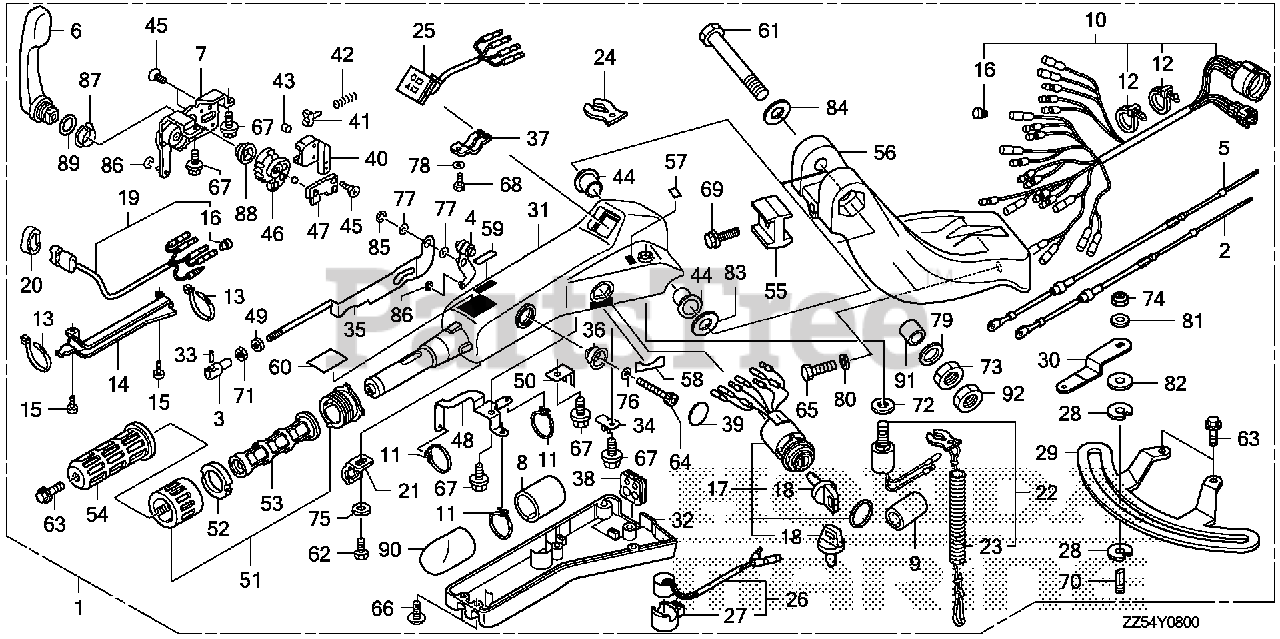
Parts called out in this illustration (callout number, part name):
1	HANDLEBAR KIT *NH282MU* (OYSTER SILVER METALLIC-U)
2	CABLE, THROTTLE
3	PIVOT, THROTTLE CABLE
4	ARM, THROTTLE
5	CABLE, SHIFT
6	LEVER, SHIFT
7	FRAME ASSY., SHIFT
8	TUBE (38.1X40)
9	TUBE
10	CABLE ASSY., LONG HANDLE (A)
11	BAND (CONVEX CV-150)
12	BAND (CONVEX CV-200)
13	BAND (CONVEX)
14	COVER, WIRE
15	SCREW
16	PLUG, CONNECTOR (INNER)
17	SWITCH ASSY., COMBINATION
18	KEY ASSY., COMBINATION SWITCH (35100-ZV5-003 ONLY)
19	SWITCH ASSY., POWER TILT
20	GROMMET
21	HOLDER, SWITCH
22	SWITCH ASSY., EMERGENCY STOP
23	WIRE, EMERGENCY
24	CLIP, EMERGENCY LOCK
25	LAMP ASSY., INDICATOR
26	BUZZER ASSY., WARNING
27	SUSPENSION, WARNING BUZZER
28	BLOCK, FRICTION
29	PLATE, FRICTION
30	LEVER, FRICTION
31	HOUSING *NH282MU* (OYSTER SILVER METALLIC-U)
32	COVER, HANDLEBAR (LOWER)
33	PIN, THROTTLE CABLE
34	BRACKET, CABLE
35	PLATE ASSY., LOCK
36	STOPPER
37	PLATE, GUIDE
38	GROMMET
39	CAP
40	GUIDE, SPRING
41	ACTUATOR
42	SPRING, COIL
43	ROLLER
44	BUSH, HANDLEBAR
45	SCREW (M5X14)
46	GEAR, SHIFT
47	PLATE, BALL GUIDE
48	BRACKET
49	ROD, GROMMET
50	CLAMP, BRACKET
51	GRIP ASSY., THROTTLE FRICTION
52	PAD, THROTTLE FRICTION
53	PIPE, GRIP
54	RUBBER, GRIP
55	BLOCK, HEIGHT ADJUSTER
56	BRACKET, STEERING *NH282MU* (OYSTER SILVER METALLIC-U)
57	MARK, EMERGENCY SWITCH INDICATION
57	MARK, EMERGENCY SWITCH INDICATION (EU)
58	MARK, STARTER (ENGLISH)
59	MARK, CHANGE
60	MARK, THROTTLE (ENGLISH)
61	BOLT, HEX. (12X80)
62	BOLT (M5X8)
63	BOLT, FLANGE (6X12)
64	BOLT (M8X50)
65	BOLT, HEX. (10X32)
66	BOLT (M5X12)
67	BOLT (M6X12)
68	BOLT (M5X12)
69	BOLT, FLANGE (8X28)
70	BOLT, STUD (8X26)
71	NUT, HEX. (5MM)
72	NUT, HEX. (16MM)
73	NUT, HEX. (12MM)
74	NUT, SELF-LOCK (8MM)
75	WASHER (5MM)
76	WASHER (8MM)
77	WASHER (10MM)
78	WASHER (5MM)
79	WASHER, WAVE (14MM)
80	WASHER (10MM)
81	WASHER (8MM)
82	WASHER, NYLON (8MM)
83	WASHER, PLAIN (12MM)
84	WASHER, PLAIN (12MM)
85	E-RING
86	E-RING
87	BEARING
88	BEARING
89	O-RING (20.6X1.9)
90	TUBE, CORD (40MM)
91	COLLAR, DISTANCE (12.2X23X16)
92	NUT, HEX. (12MM)
